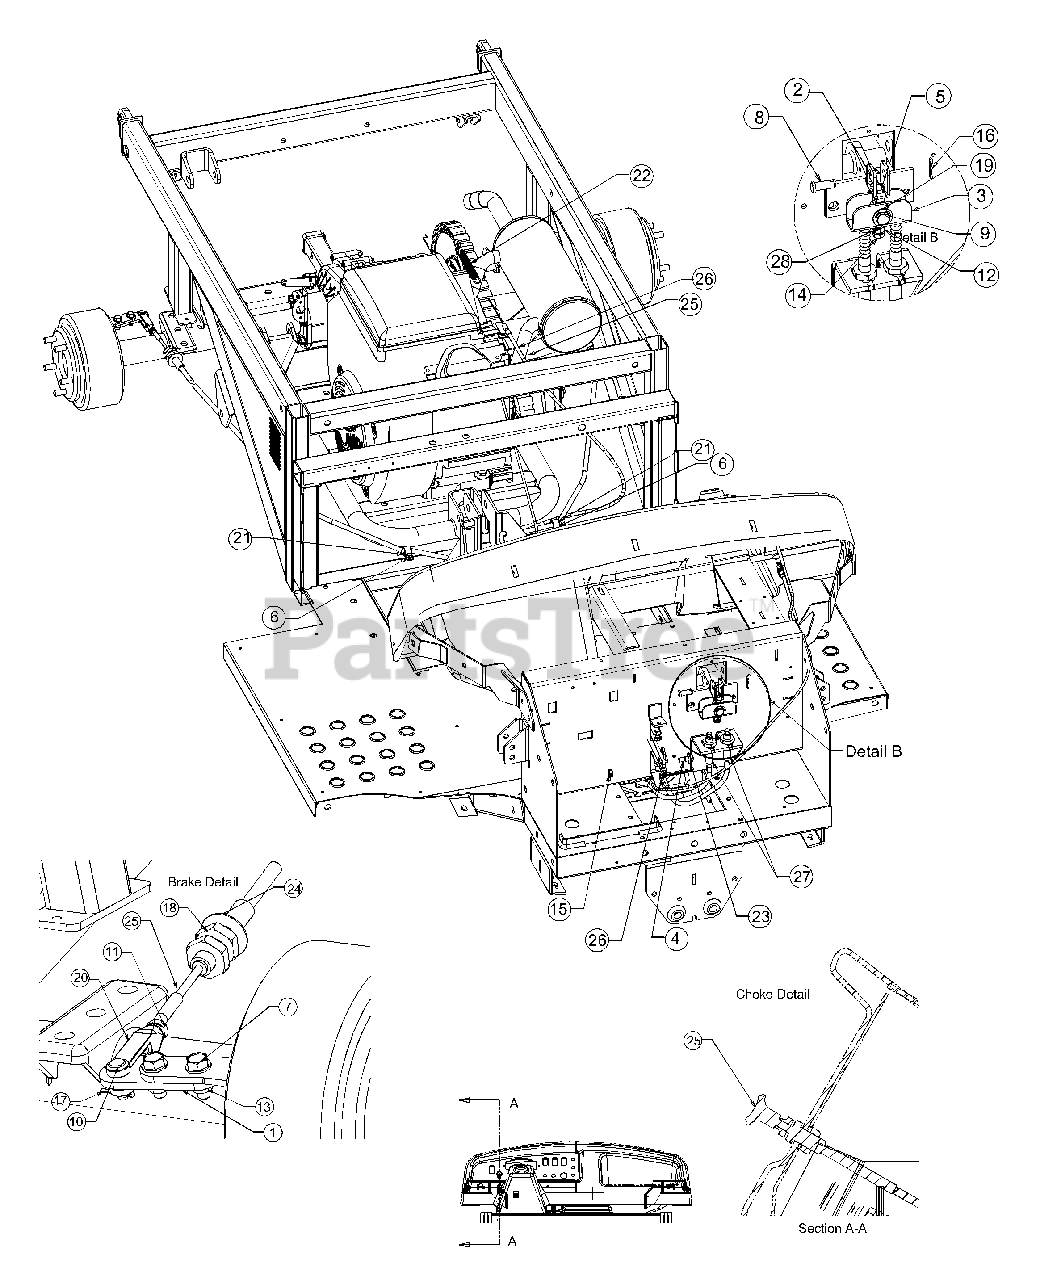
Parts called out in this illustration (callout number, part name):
1	Plate, Arm Brake
2	Mount,Cable
3	Bracket, Equalizer
4	Screw, Shoulder, .375 x .375
5	Screw, 5/16-18 x 2.5
6	Screw, Self-Tapping
7	Washer, 5/16-18 x .875
8	Pin, Clevis 375 x .969
9	Pin, Clevis .625 OD x 1.37
10	Pin, Clevis .312 OD x 1.0
11	Nut, Jam 5/16-24
12	Nut, Hex 5/16-18
13	Nut, Flange Lock 5/16-18
14	Nut, Jam 5/16-18
15	Hexlock Nut, 5/16-18
16	Pin, Cotter, .072 x 1.13
17	Pin, Cotter 3-32 x .750
18	E-Ring for .500 Dia Shaft
19	E-Ring.625 Shaft
20	Yoke, 5/16-24
22	Extension Spring
23	Washer, .349 x .879 x .063
24	Flat Washer, 1.0 OD x .56 ID x .040
25	Cable, Control, Choke
26	Cable, Control, Throttle
27	Cable, Control, Brake
28	Spacer, .466 OD x .443
